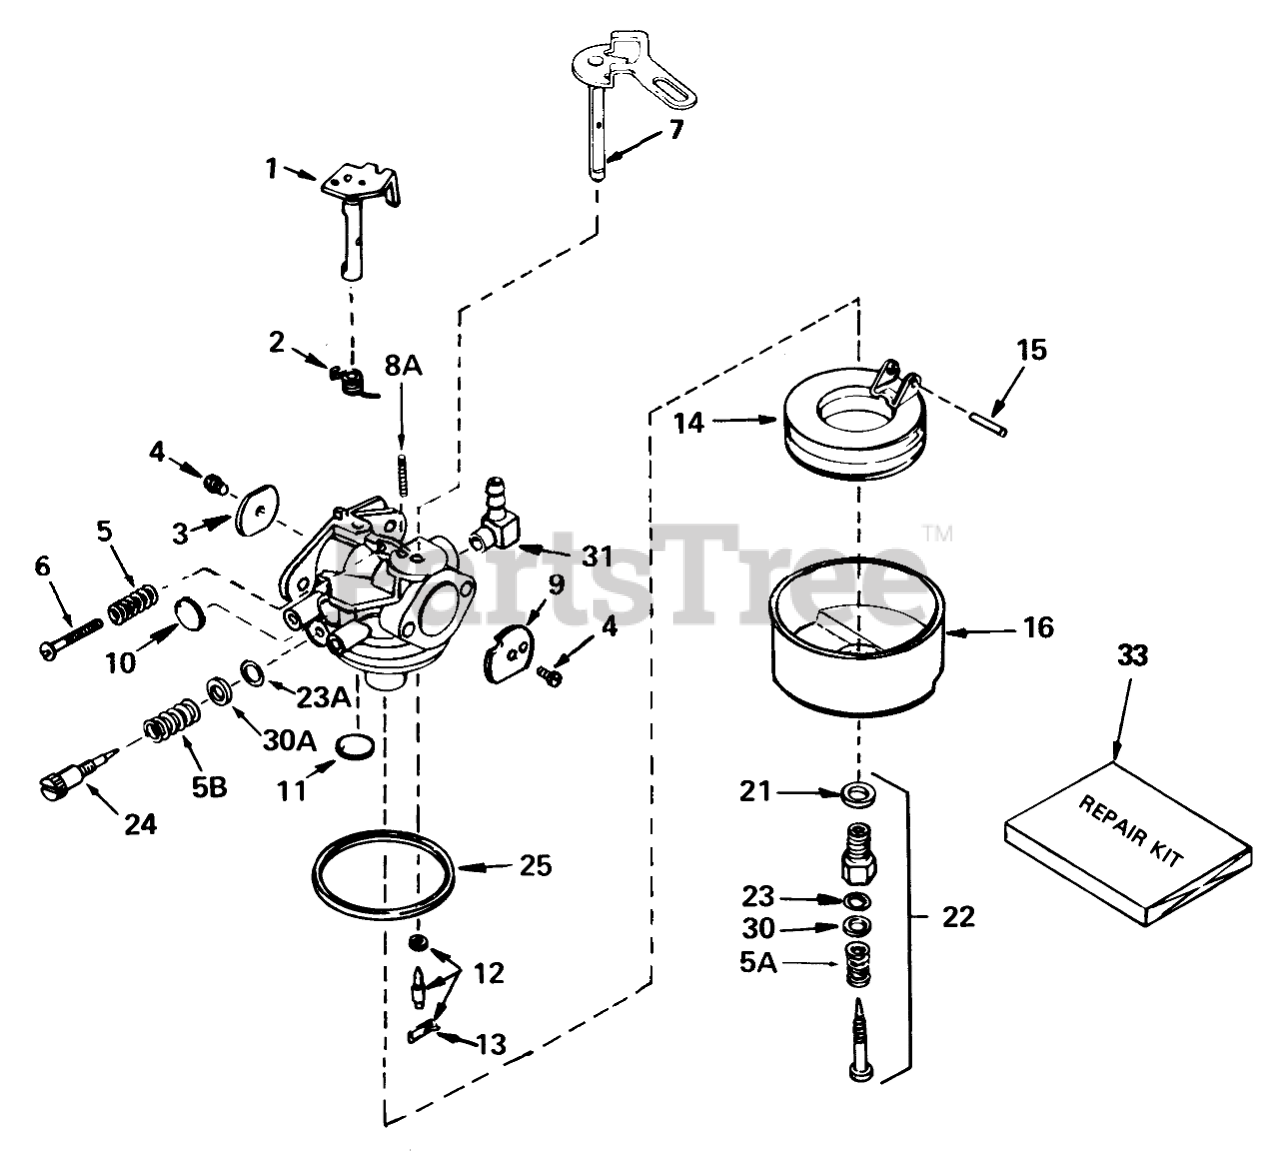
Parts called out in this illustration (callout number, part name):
1	Throttle Shaft and Lever ASM
2	Spring-Return, Throttle
3	Shutter-Throttle
4	Screw-Shutter
5	Spring-Tension
5B	Spring-Tension
6	Screw-Throttle Crack Screw / Idle Speed
7	Choke Shaft and Lever Asm
8	Spring-Positioning, Choke
9	Shutter-choke
10	Plug-Welch, Idle Mixture Well
11	Plug-Welch, Atmospheric Vent
12	Inlet Needle-Seat & Clip Assy. (Incl. Ref. #13)
13	Clip-Spring
14	Float
15	Shaft-Float
16	Bowl-Float (no drain)
21	Washer-Bowl Nut
22	Adjusting Screw Assy.-Main (Incl. Ref. #5A, 21, 23 & 30)
23	"O"Ring
23A	"O"Ring
24	Screw-Idle
25	O Ring-Bowl, Float
31	Fitting-Fuel
33	Kit-Repair
